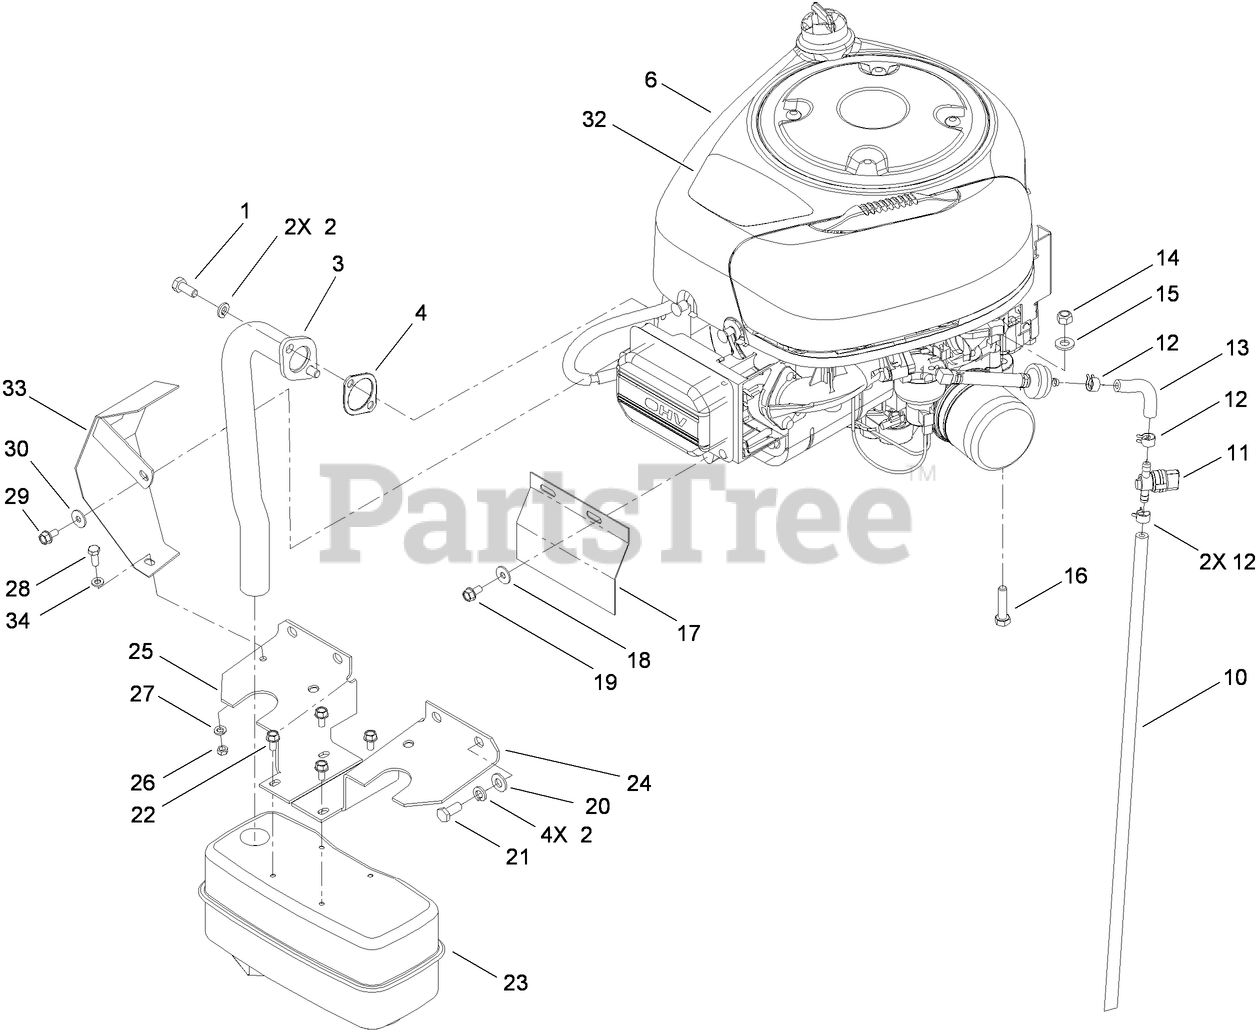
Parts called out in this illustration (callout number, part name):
1	SCREW-HH
3	TUBE-EXHAUST
4	GASKET-EXHAUST
10	LINE-FUEL
11	VALVE-TANK, FUEL
12	CLAMP-LINE, FUEL
13	LINE-FUEL
14	NUT-LOCK, NI
15	WASHER-PLAIN
16	SCREW-HH
17	COVER-FRONT
18	WASHER-FLAT
20	WASHER-PLAIN
21	SCREW-HH
23	MUFFLER
24	GUARD-MUFFLER, LH
25	GUARD-MUFFLER, RH
26	NUT-HEX
27	WASHER-SPRING
28	SCREW-HH
30	WASHER-FLAT
32	DECAL-ENGINE, I/C
33	Cover-Manifold, Exhaust
34	WASHER-FLAT
